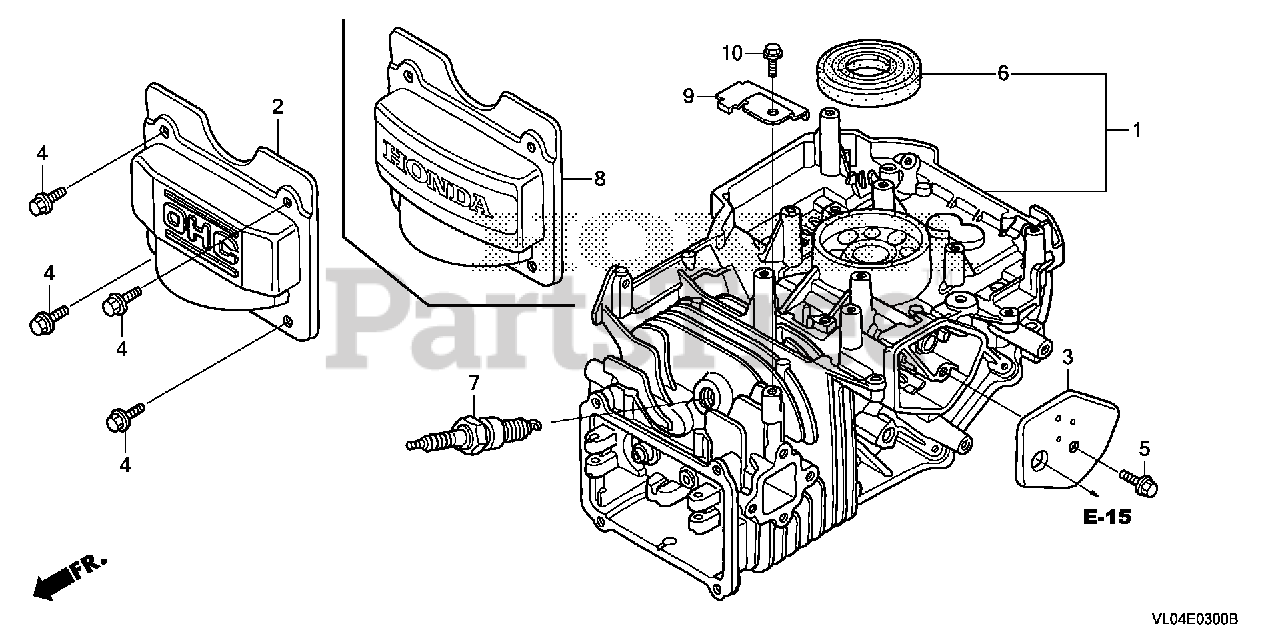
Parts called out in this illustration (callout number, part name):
1	CYLINDER ASSY.
3	COVER, BREATHER (Honda Code 5580006). (BREATHER VALVE ASSY.)
4	BOLT, FLANGE (6X12) (CT200)
5	BOLT, FLANGE (6X14)
6	OIL SEAL (25.4X62X6)
7	SPARK PLUG (BPR5ES) (NGK)
8	COVER, HEAD
9	BRACKET, REGULATOR
10	BOLT, FLANGE (6X14)
